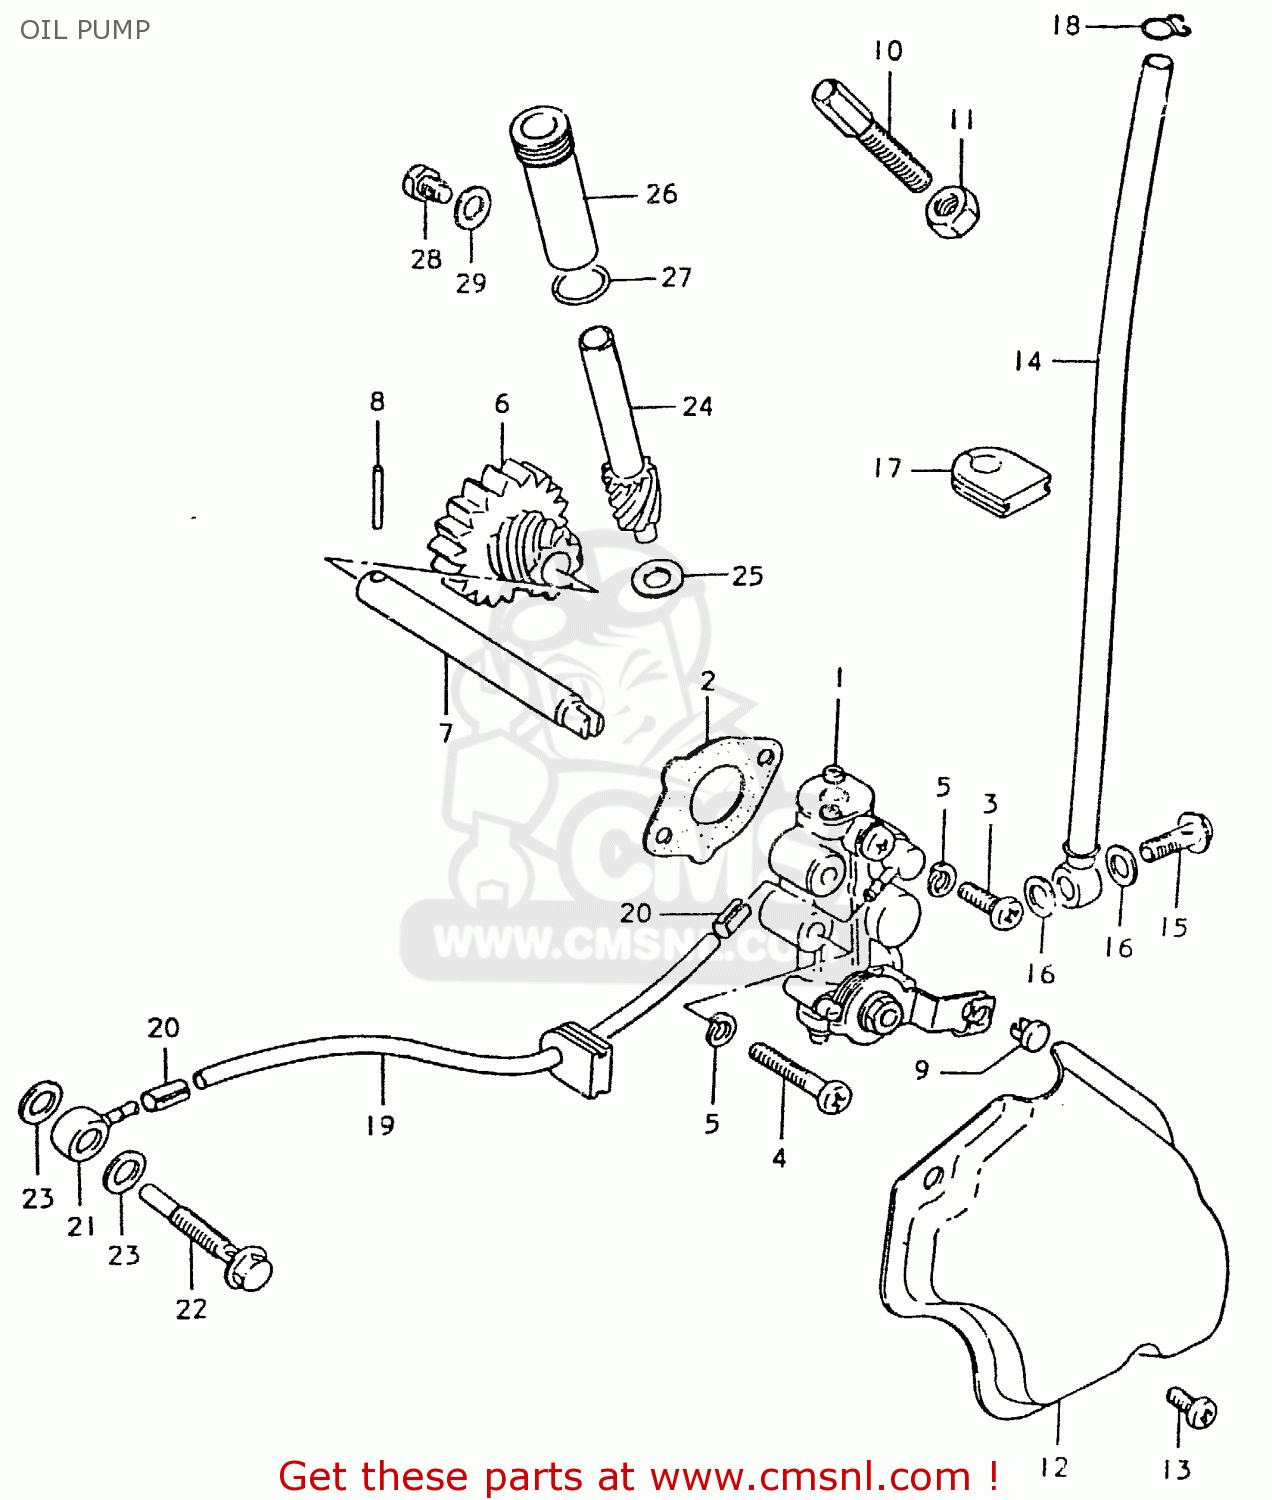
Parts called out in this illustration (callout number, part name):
1	PUMP ASSEMBLY,OIL
2	GASKET,OIL PUMP (NAS)
3	SCREW
4	SCREW
5	LOCK WASHER
6	GEAR,OIL PUMP DRIVE
7	SHAFT,OIL PUMP DRIVE
8	PIN(2.5X19.8)
9	TERMINAL,CABLE
10	BOLT
11	NUT
12	CAP,OIL PUMP INSPECTION
13	SCREW
14	HOSE,OIL NO.1
15	UNION BOLT
16	GASKET(6.2X11X1).2 (NAS)
17	GROMMET
18	CLIP
19	HOSE,OIL NO.2
20	CLIP
21	UNION
22	UNION
23	GASKET(6.2X11X1).2 (NAS)
24	GEAR,TACHOMETER DRIVEN(NT:10)
25	WASHER(8X13.7X1)
26	SLEEVE,TACHOMETER DRIVE GEAR
27	O RING(D:1.3,ID:9.6)
28	BOLT
29	WASHER
